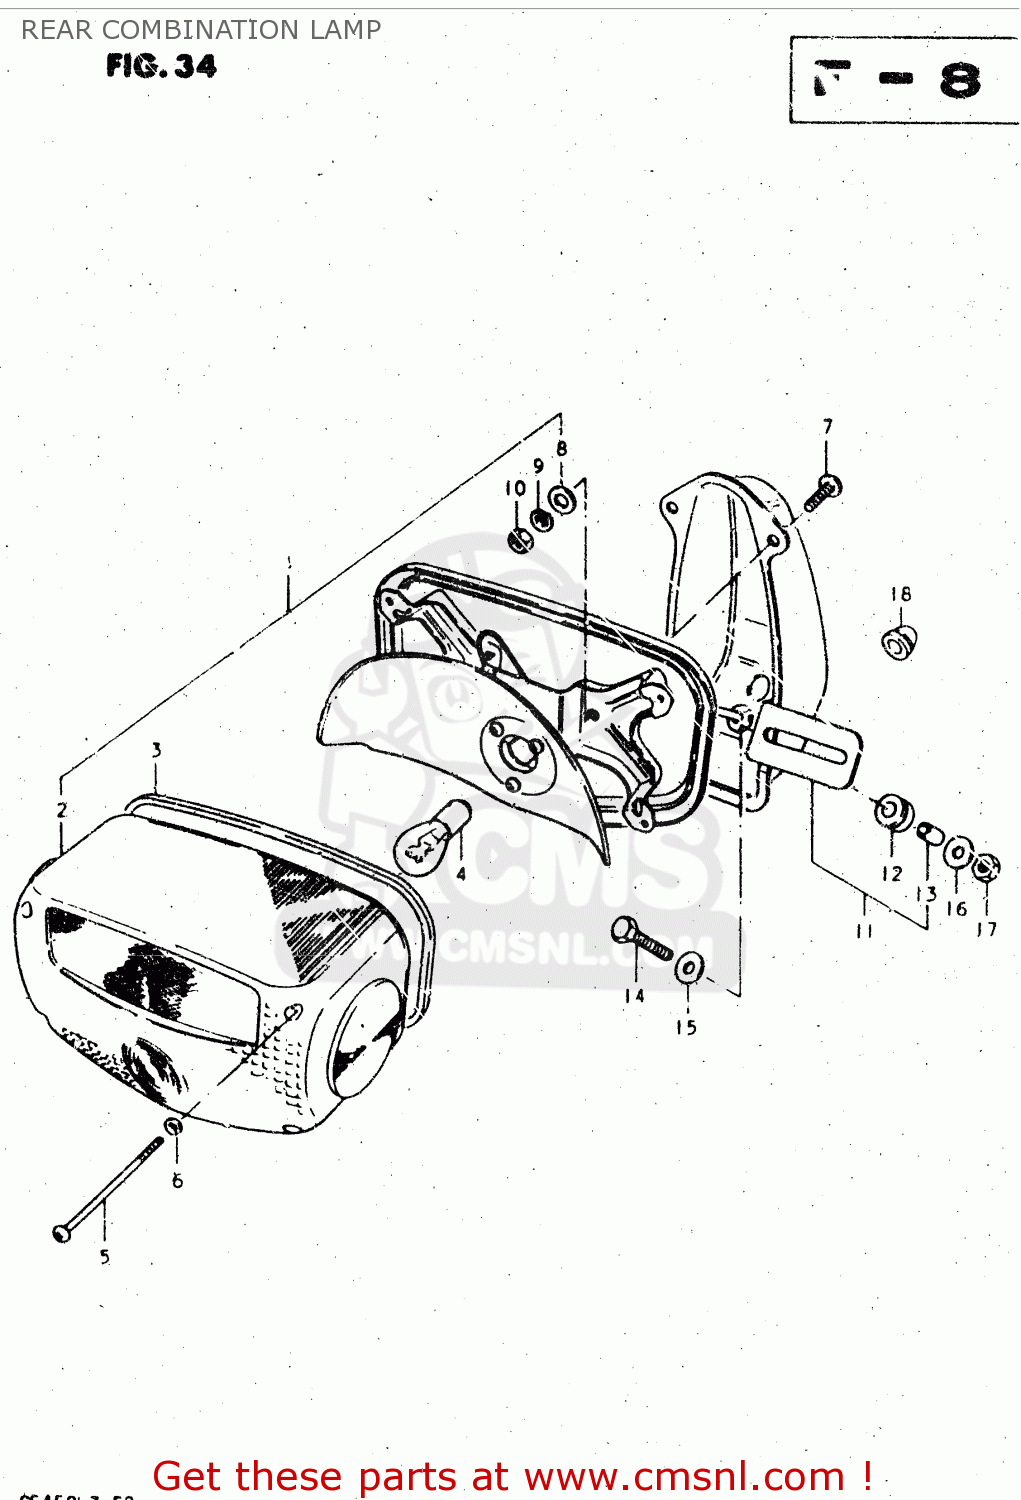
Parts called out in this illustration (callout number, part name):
1	LAMP UNIT, TAIL
2	LENS,REAR COMBINATION LAMP
3	GASKET (NAS)
4	BULB(12V21/5W)
5	SCREW (4X55)
6	GASKET (NAS)
7	SCREW 6X12
8	WASHER
9	LOCK WASHER
10	NUT
11	BRACKET ASSY
12	CUSHION
13	SPACER
14	BOLT
15	WASHER (6.5X20X1.2)
16	WASHER
17	NUT
18	GROMMET
